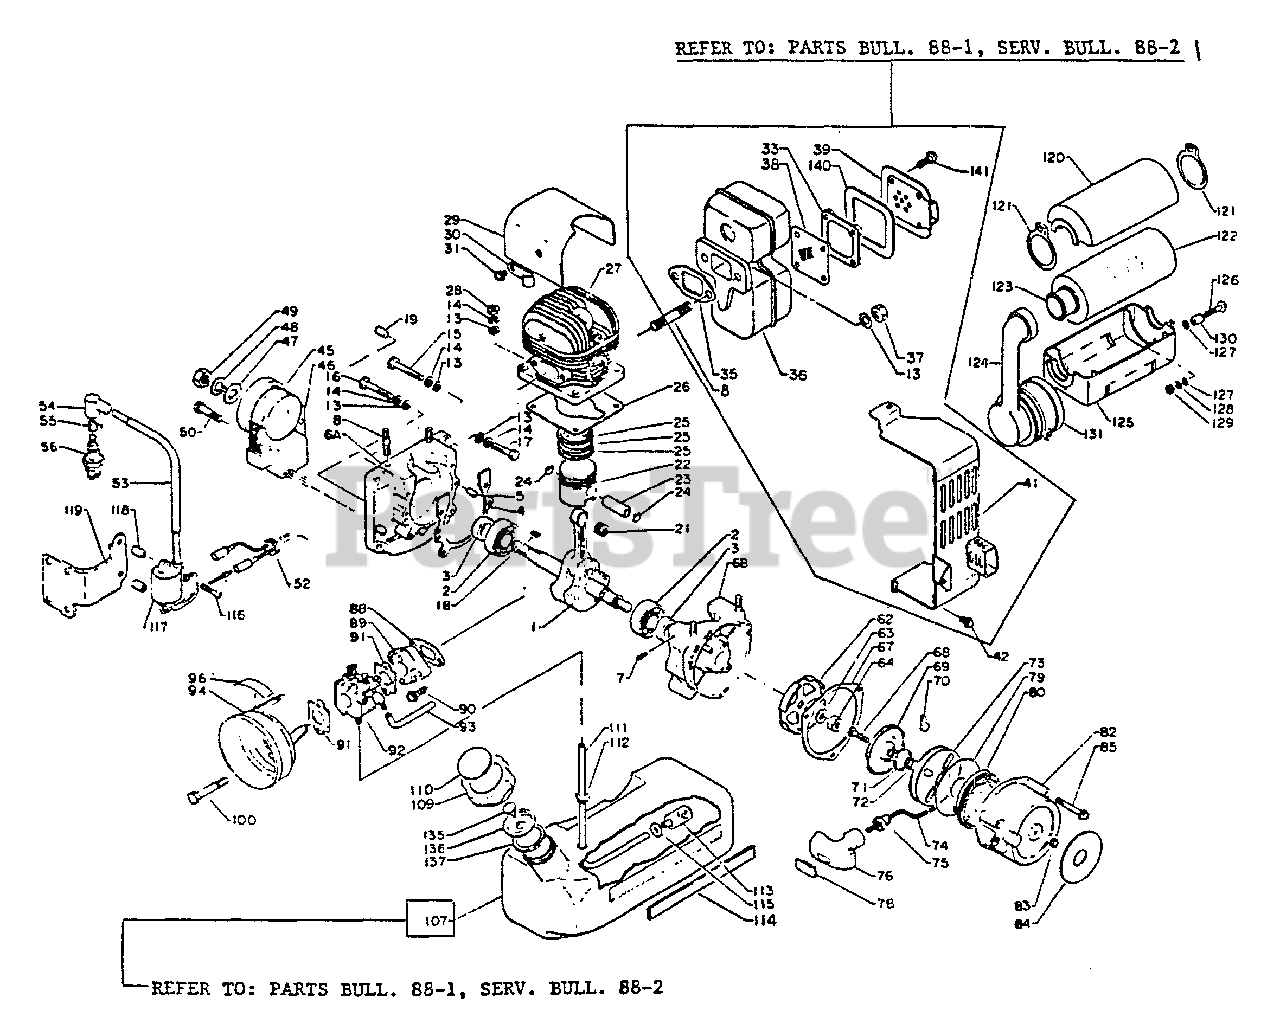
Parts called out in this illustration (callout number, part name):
1	CRANKSHAFT ASSY
2	BEARING, BALL - 6202
3	SEAL, OIL
4	GASKET, CRANKCASE
5	PIN - LOCATING
6	CRANKCASE KIT
6A	CRANKCASE KIT
7	CONNECTOR
13	WASHER - 6
14	LOCKWASHER - 6
17	BOLT - 6X25
21	BEARING, NEEDLE
22	PISTON
23	PIN, PISTON
24	RING, RETAINING - 8
25	RING, PISTON
26	GASKET, CYLINDER
27	CYLINDER
28	LOCKNUT - 6
29	SHIELD, CYLINDER
31	BOLT - 6X10
33	RETAINER, SCREEN
35	GASKET, EXHAUST
38	SCREEN, SPARK ARRESTOR
39	GUIDE, EXHAUST
41	COVER, EXHAUST
42	SCREW - 5X12
45	FLYWHEEL
46	COIL, IGNITION
48	LOCKWASHER
50	SCREW - 5X25
54	CAP, SPARK PLUG
55	TERMINAL, SPARK PLUG CAP
56	SPARK PLUG -- BM-6A
62	CATCHER, PAWL
63	WASHER, CLUTCH
67	GASKET, STARTER
69	PLATE, FRICTION
70	PAWL, STARTER
71	SPRING, RETURN
72	SPRING
73	REEL, ROPE
74	ROPE, STARTER - 4X880
75	GUIDE, ROPE
76	GRIP, STARTER
79	PLATE, STARTER
80	SPRING, REWIND
82	CASE, STARTER
83	NUT - 5 -- CAP
84	LABEL - ECHO
85	SCREW - 5X40
88	GASKET, INTAKE
89	INSULATOR, INTAKE
90	SCREW - 6X25
91	GASKET, INTAKE
92	CARBURETOR WA-55
93	PIPE - IMPULSE
94	CASE, AIR FILTER
96	LABEL - CHOKE
100	BOLT
107	TANK, FUEL
109	CAP ASSY
110	LABEL - FUEL MIX
111	PIPE, FUEL - SPIRAL
113	FILTER, FUEL
114	LABEL - NAME
115	WASHER - 5
116	SCREW - 4X25
117	COIL, IGNITION
120	COVER, AIR FILTER
122	FILTER, AIR
123	FILTER, AIR
124	ADAPTOR, INTAKE
125	CASE, AIR FILTER
126	BOLT
127	WASHER - 5
128	LOCKWASHER - 5
131	CLAMP
136	HOLDER, VENT
137	GASKET, CAP
140	GASKET, EXHAUST
141	SCREW - 4X14
